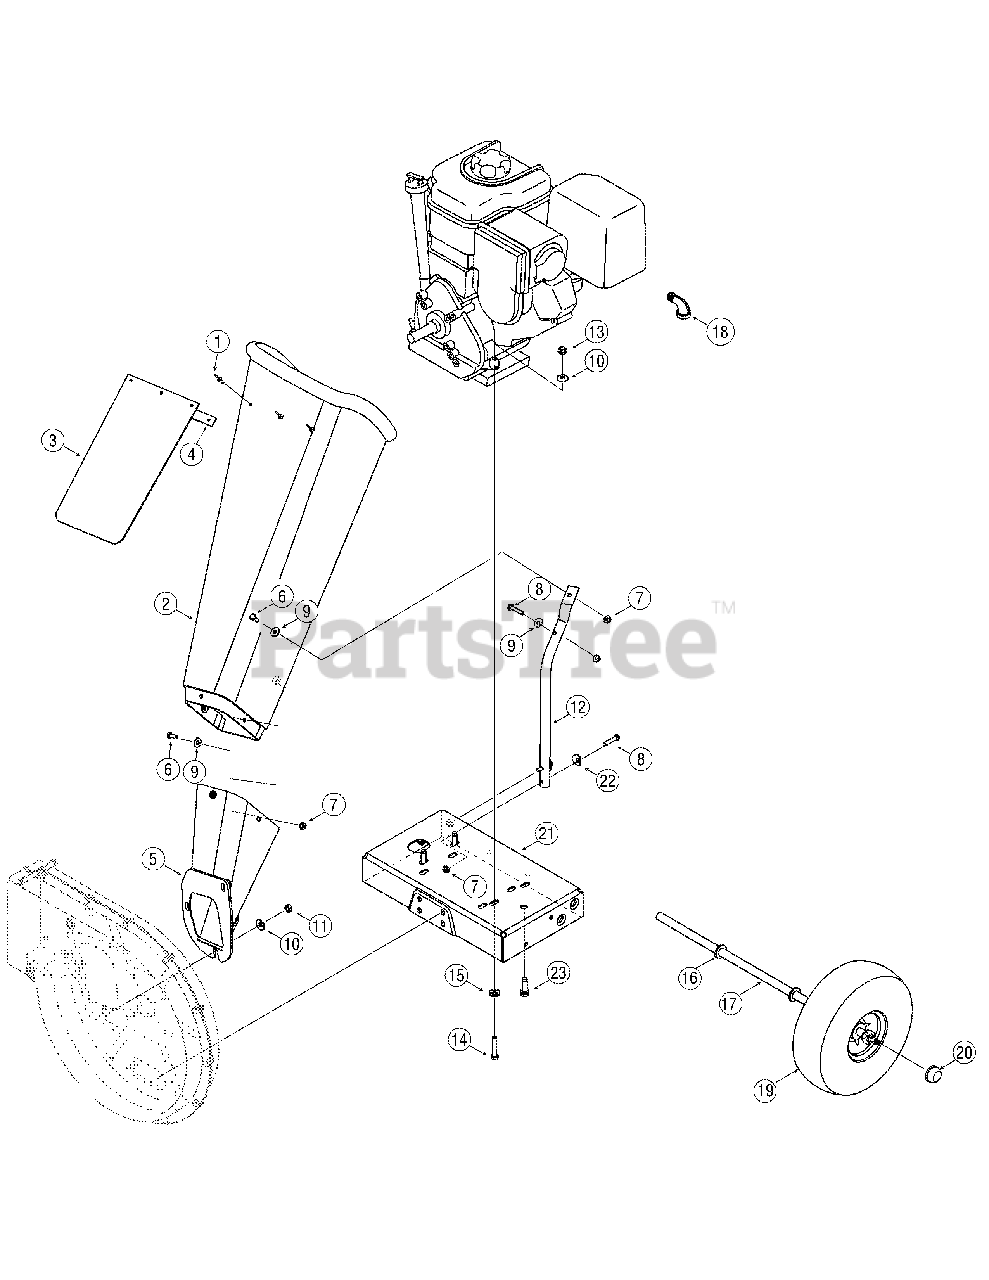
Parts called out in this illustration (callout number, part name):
1	Pop Rivet
2	Chipper Shredder Chute
3	Chute Flap
4	Chute Flap Strip
7	Hex Lock Nut 1/4-20
8	Hex Cap Screw 1/4-20 x 1.25
9	Flat Washer.28 ID x.74 OD
10	Bell Washer.340 ID x.872 OD
11	Hex Nut 5/16-18
13	Hex Lock Nut 5/16-18
14	Hex Cap Screw 5/16-18 x 1.50
15	Bell Washer 5/16 x 1.0
16	Flat Washer
17	Axle Assembly
18	Elbow Fitting
19	Wheel Complete, 10.0 x 4.0 Gray
20	Push Cap
22	Washer,.320 ID x.93 OD
23	Screw, 3/8-16 x 1.250
